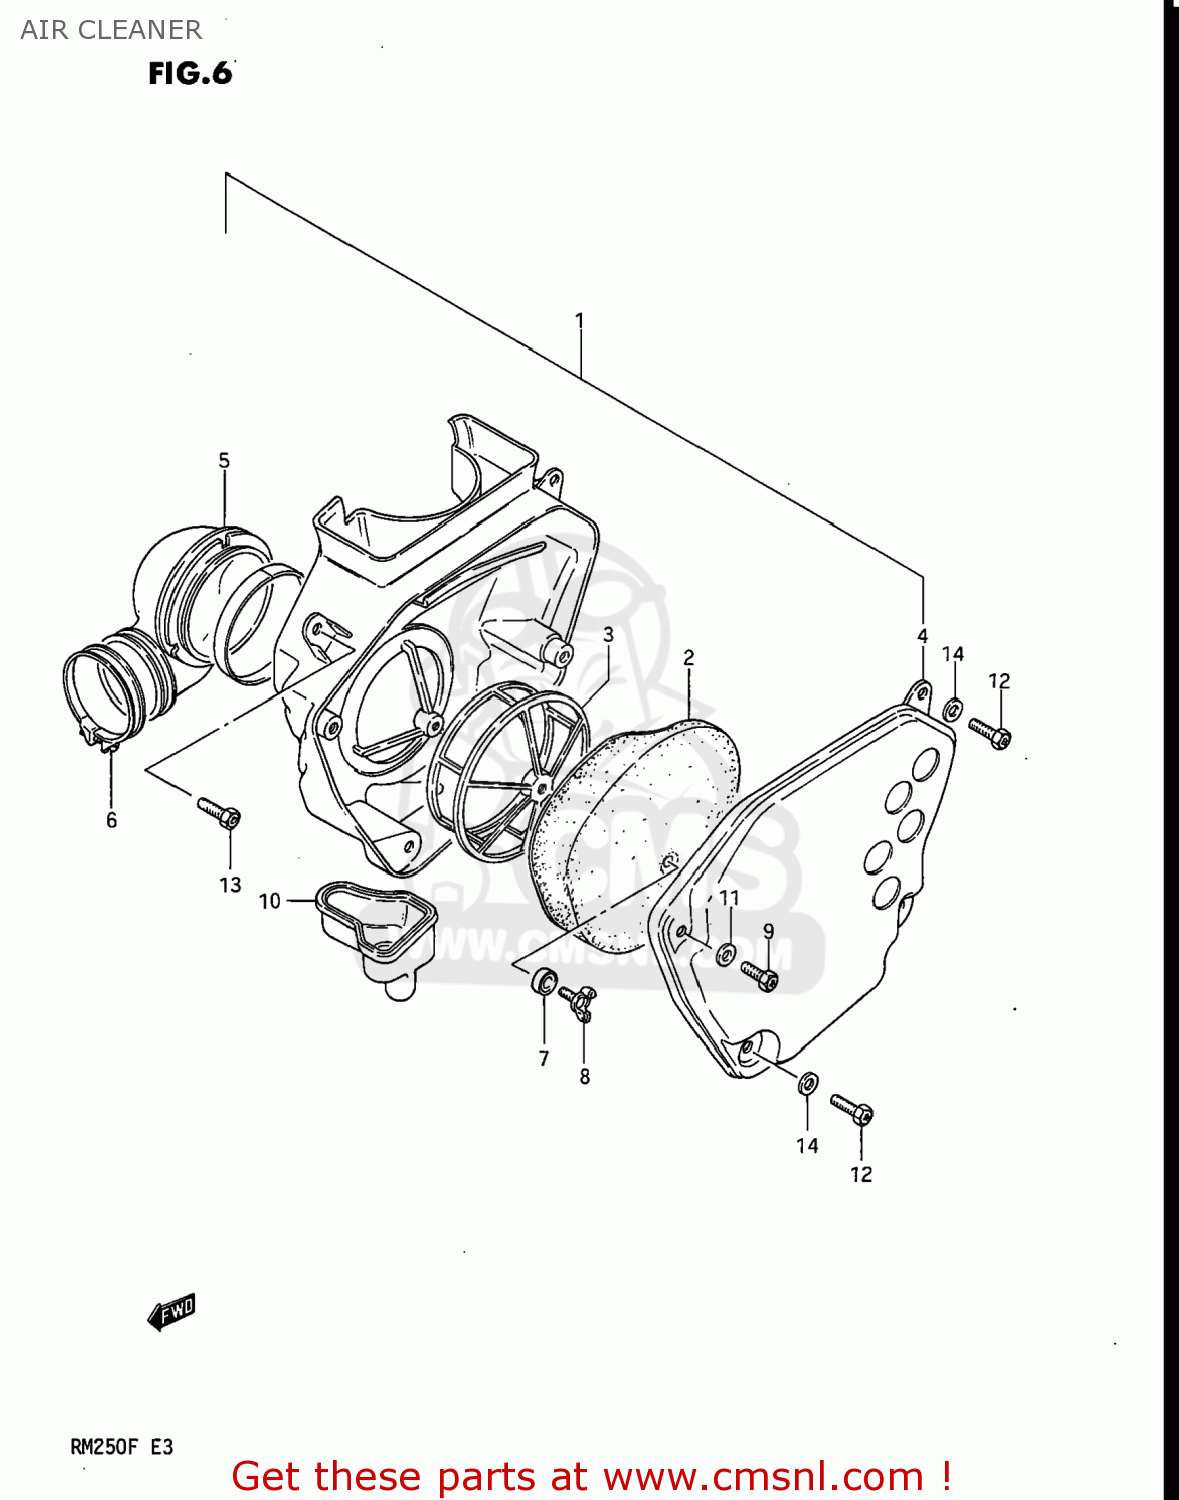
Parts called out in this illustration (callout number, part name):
1	CLEANER ASSEMBLY,AIR
2	FILTER,AIR CLEANER
3	HOLDER,FILTER
4	CAP,AIR CLEANER
5	TUBE,AIR CLEANER OUTLET
6	CLAMP
7	WASHER,FILTER HOLDER
8	BOLT,AIR CLEANER
9	SCREW
10	DRAIN TUBE
11	WASHER
12	SCREW
13	SCREW
14	WASHER
